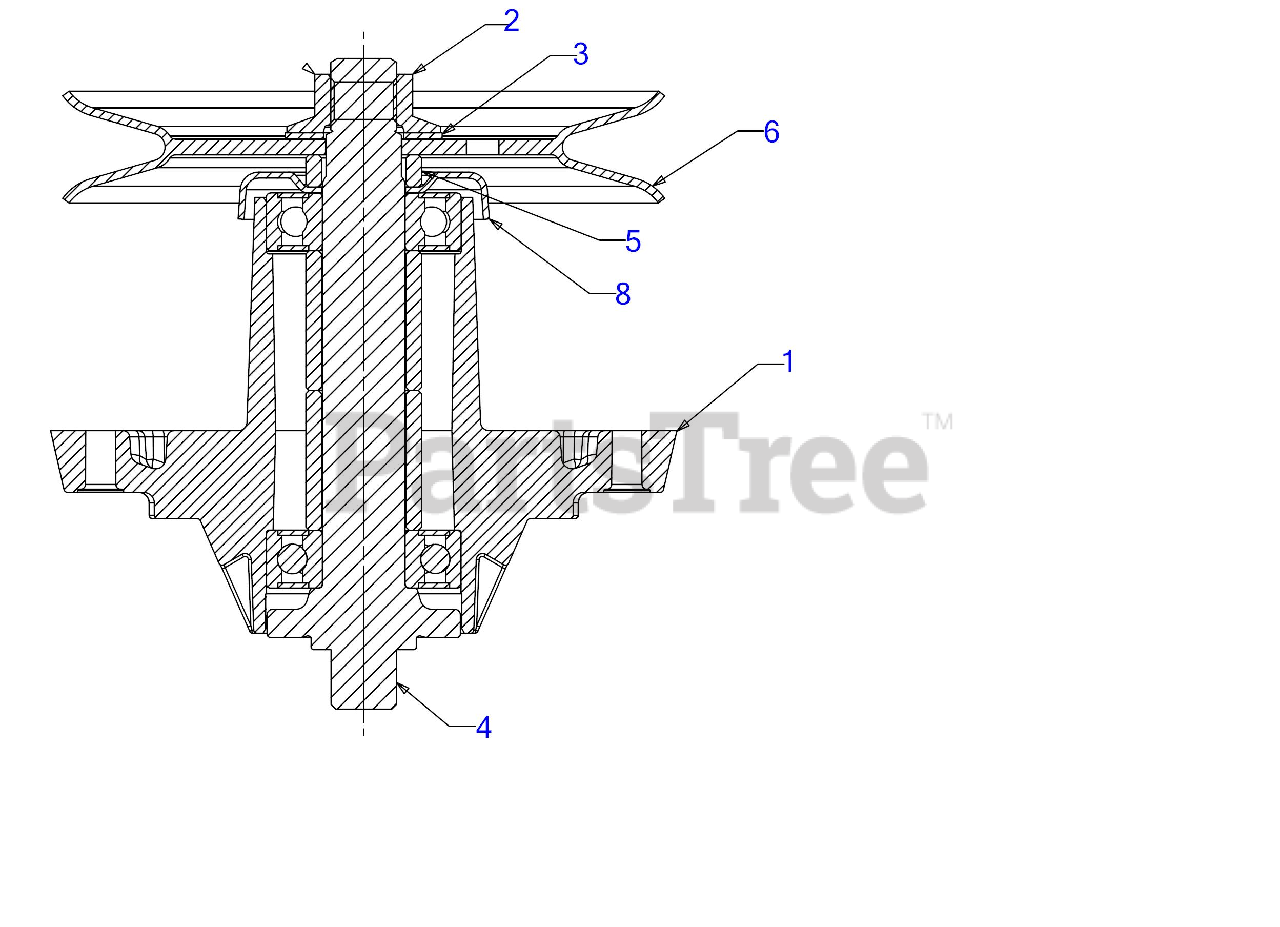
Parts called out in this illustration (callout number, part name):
1	HOUSING
1	BALL BEARING
2	FLANGE NUT 5/8-18
3	FLAT WASHER .760ID X1.49OD x .06
4	BLADE SPINDLE SHAFT
6	DECK PULLEY 5.75 DIA
8	SHIELD-BRG DECK
